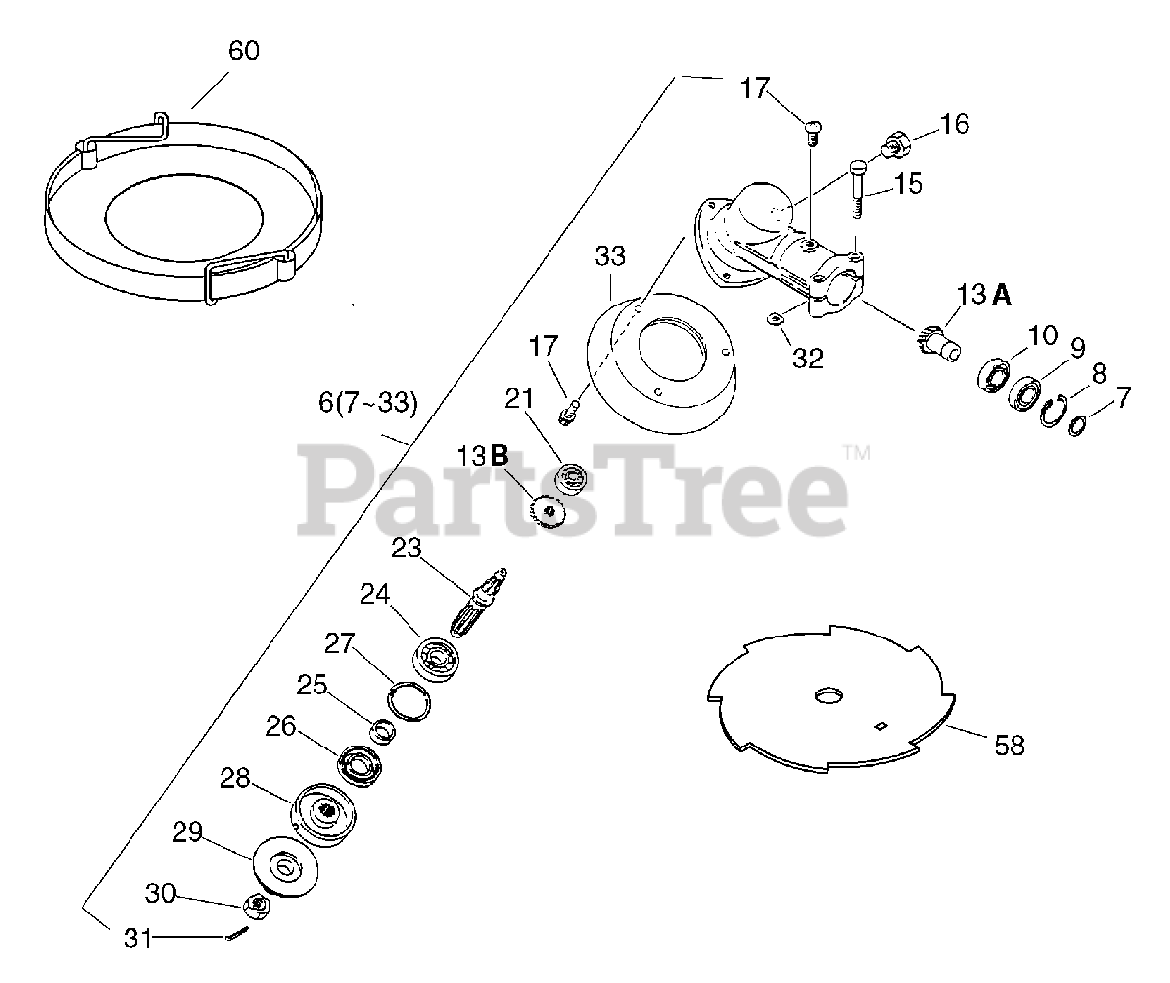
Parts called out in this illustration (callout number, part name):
6	Housing Assy, Gear
7	Circlip 10
8	Circlip 22
9	Bearing, Ball 6900Z
10	Bearing, Ball 6900
15	Bolt 5*28 (W/W,SW)
16	Bolt 8* 8
17	Screw 5*10
21	Bearing, Ball 626
23	Shaft, P.T.O.
24	Bearing, Ball 6000
27	Circlip 26
28	Plate, Adapter (U)
29	Plate, Adapter
30	Nut 10 (L-H)
31	Pin, Split 2*22
32	Washer, Shim
33	Plate, Guard (WH)
58	Blade, 8-Cutter
60	Cover Set, Cutter
